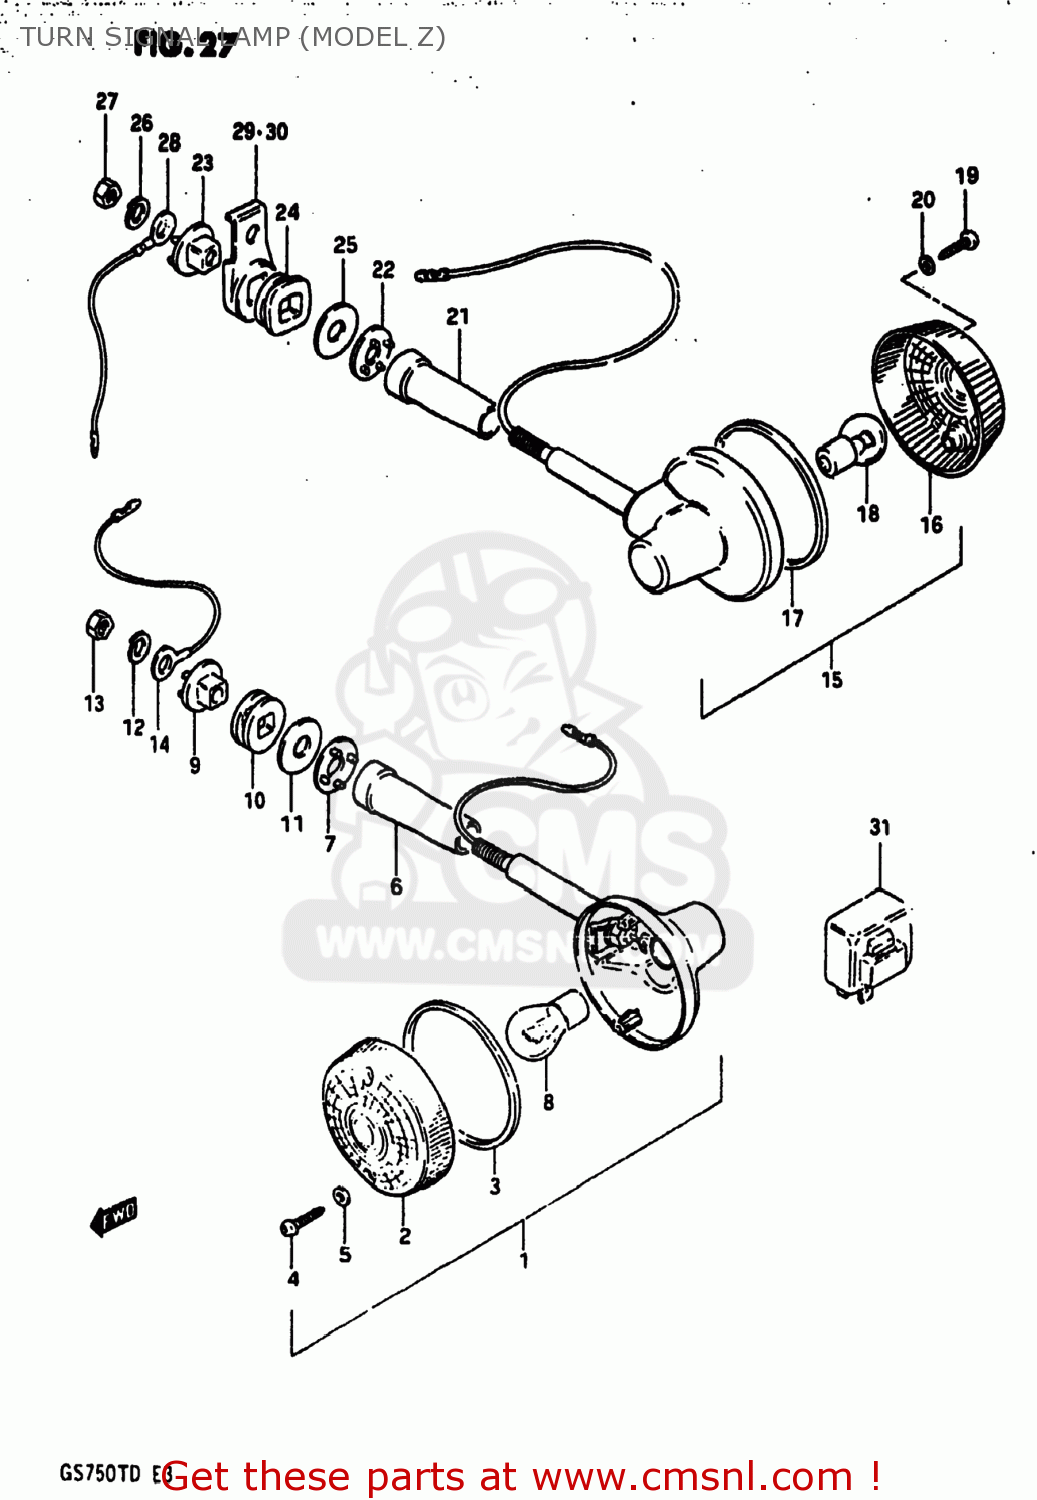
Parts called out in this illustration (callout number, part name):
1	LAMP ASSY,TURNSIGNAL
2	LENS
3	GASKET (NAS)
4	SCREW
5	GASKET (NAS)
6	COVER,STAY
7	SPACER
8	BULB(12V23W,STANLEY,A4577A)
9	SPACER
10	CUSHION
11	WASHER (10.5X30X2.3)
12	LOCK WASHER
13	NUT
14	LEAD WIRE,EARTH
15	LAMP ASSY,RR TURNSIGNAL
16	LENS
17	GASKET (NAS)
18	BULB(12V23W,STANLEY,A4577A)
19	SCREW
20	GASKET (NAS)
21	COVER
22	SPACER
23	SPACER
24	CUSHION
25	WASHER (10.5X30X2.3)
26	LOCK WASHER
27	NUT
28	LEAD WIRE,EARTH
29	BRACKET,REAR TURN SIGNAL
30	BRACKET,REAR TURN SIGNAL
31	RELAY,TURN SIGNAL
